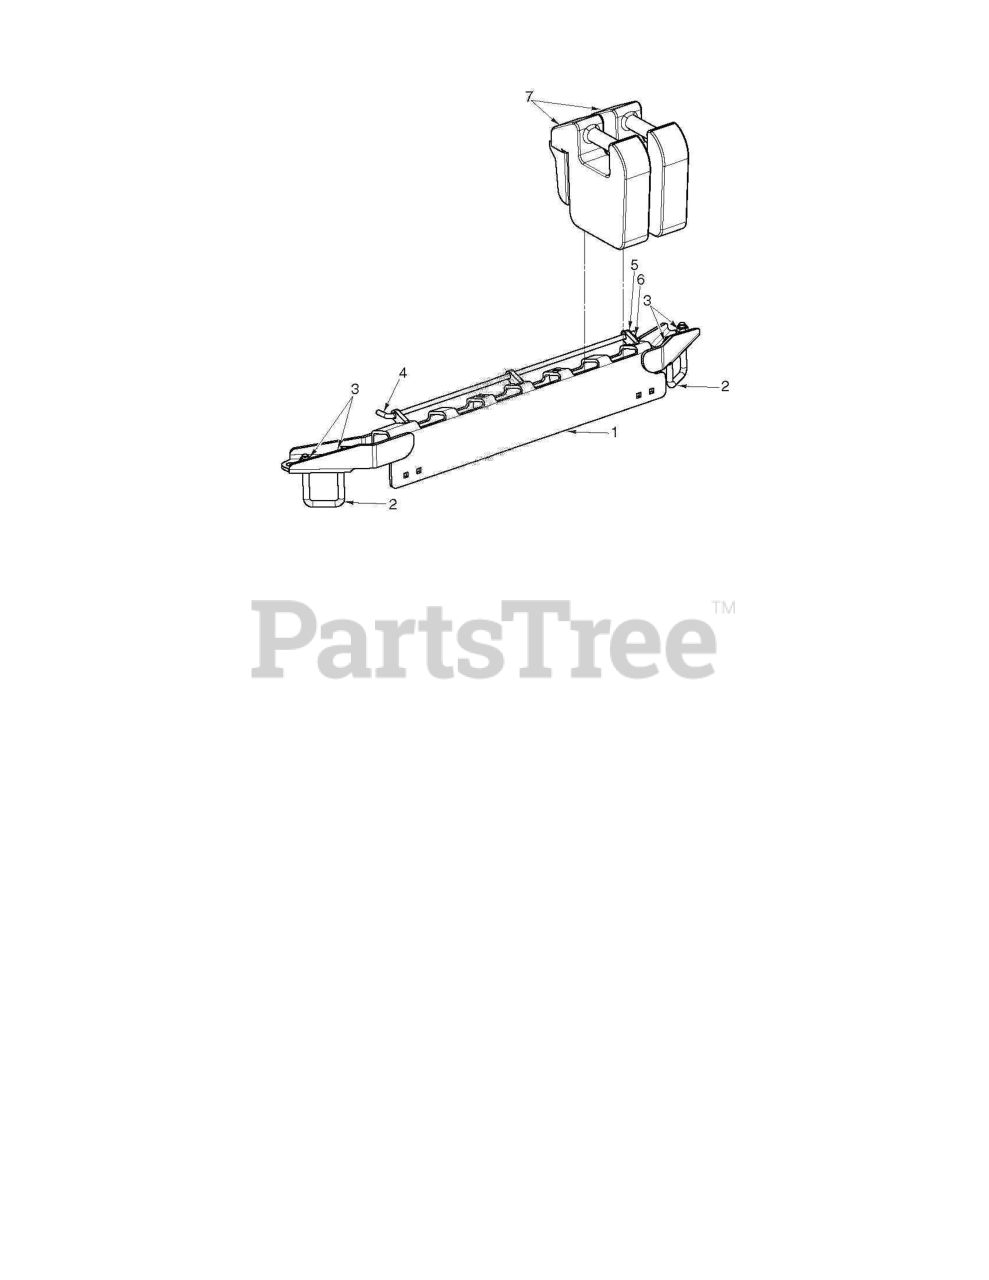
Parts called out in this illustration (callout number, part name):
1	Brackets
2	U-BOLT.SQUARE.1/2-13.GR5
3	NUT 1/2-13 HEX FLANGE NYLOK CL
4	ROD.LATCH.BLK
5	WASHER PLAIN WASHER 3/8 X 0.08
6	Pins
7	FRONT WEIGHT CAST PZ DFS
